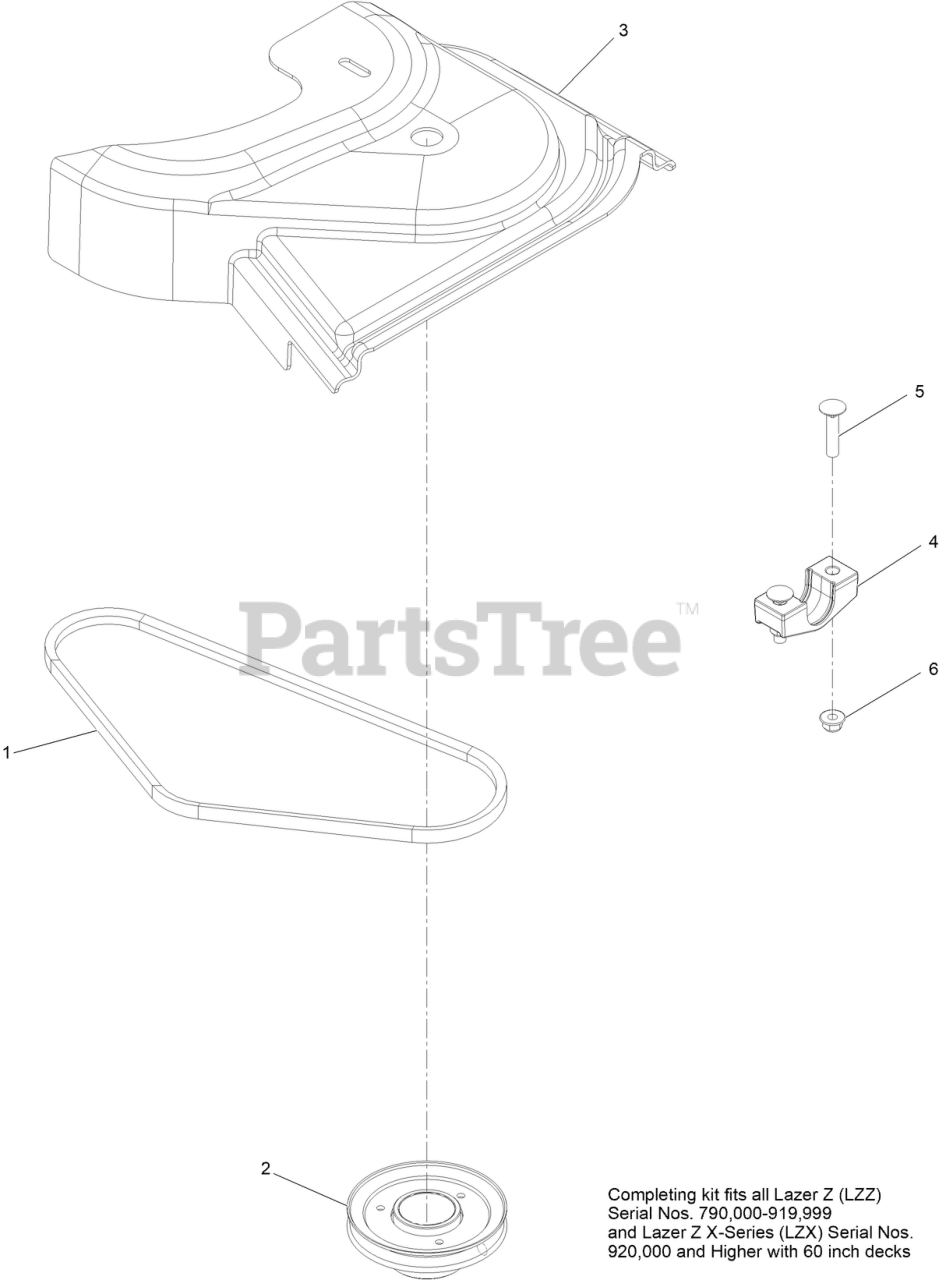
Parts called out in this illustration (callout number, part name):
2	SHEAVE,DRIVE LZUV 606
3	COVER,BELT UV 60
4	SUPPORT-BEARING CROSS SHAFT
5	SCREW-CARR
6	NUT-HF, NI
